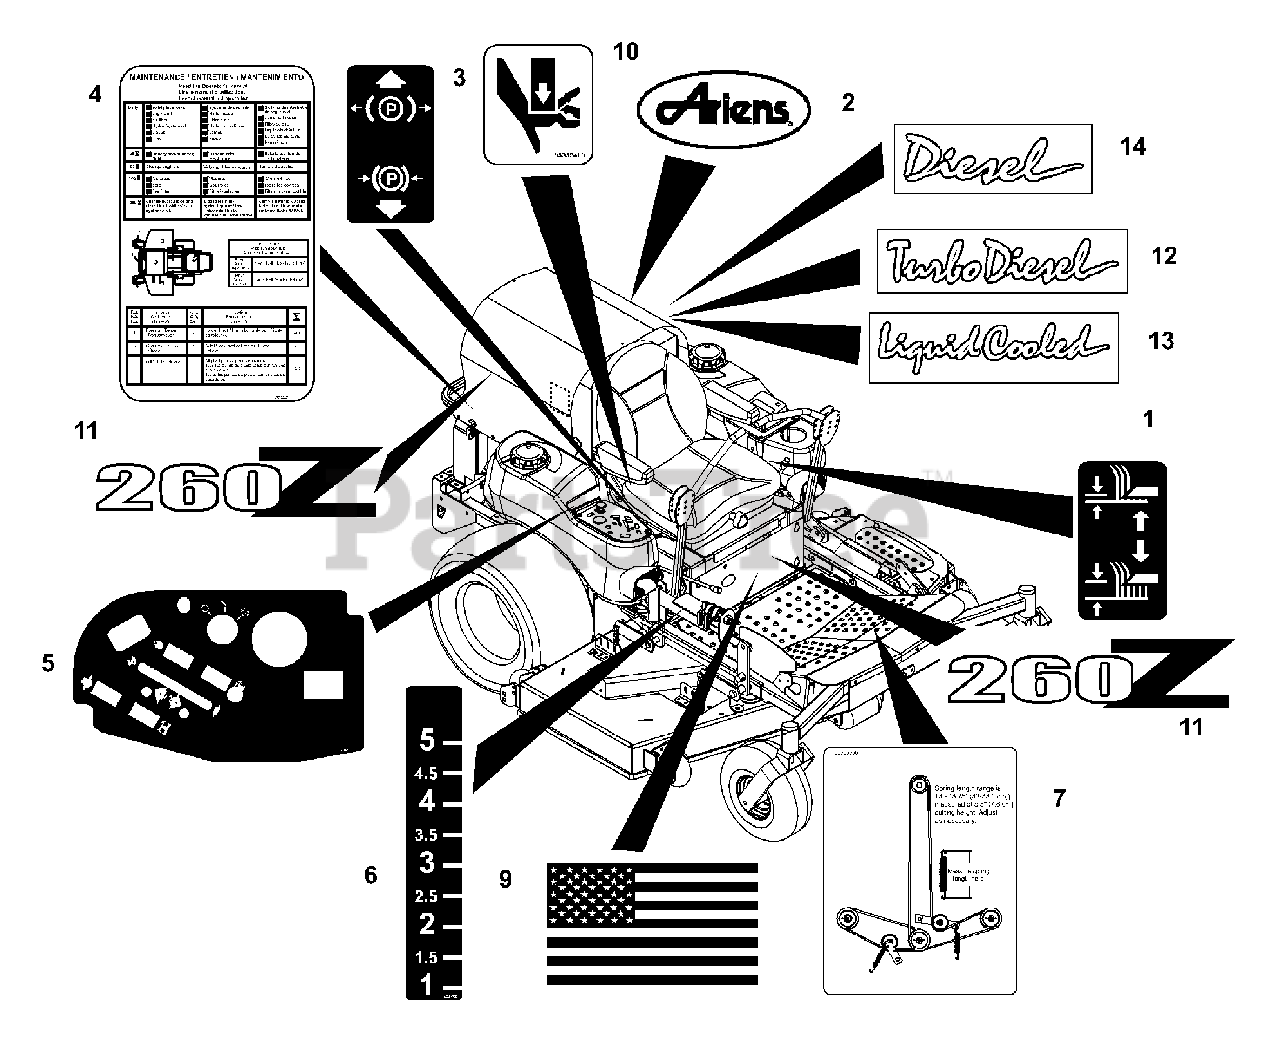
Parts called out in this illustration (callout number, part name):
1	DECAL- LIFT LEVER
2	DECAL, ARIENS
3	DECAL, PARKING BRAKE LEVER
4	DECAL- SERVICE INSTRUCTIONS
5	DECAL, CONTROL PANEL
6	DECAL, HEIGHT OF CUT
7	DECAL, BELT DIAGRAM
8	DECAL, PM-260Z
9	DECAL, AMERICAN FLAG
10	DECAL, PINCH POINT
11	DECAL, PM-260Z
12	DECAL, TURBO DIESEL
13	DECAL, LIQUID COOLED
14	DECAL, DIESEL
